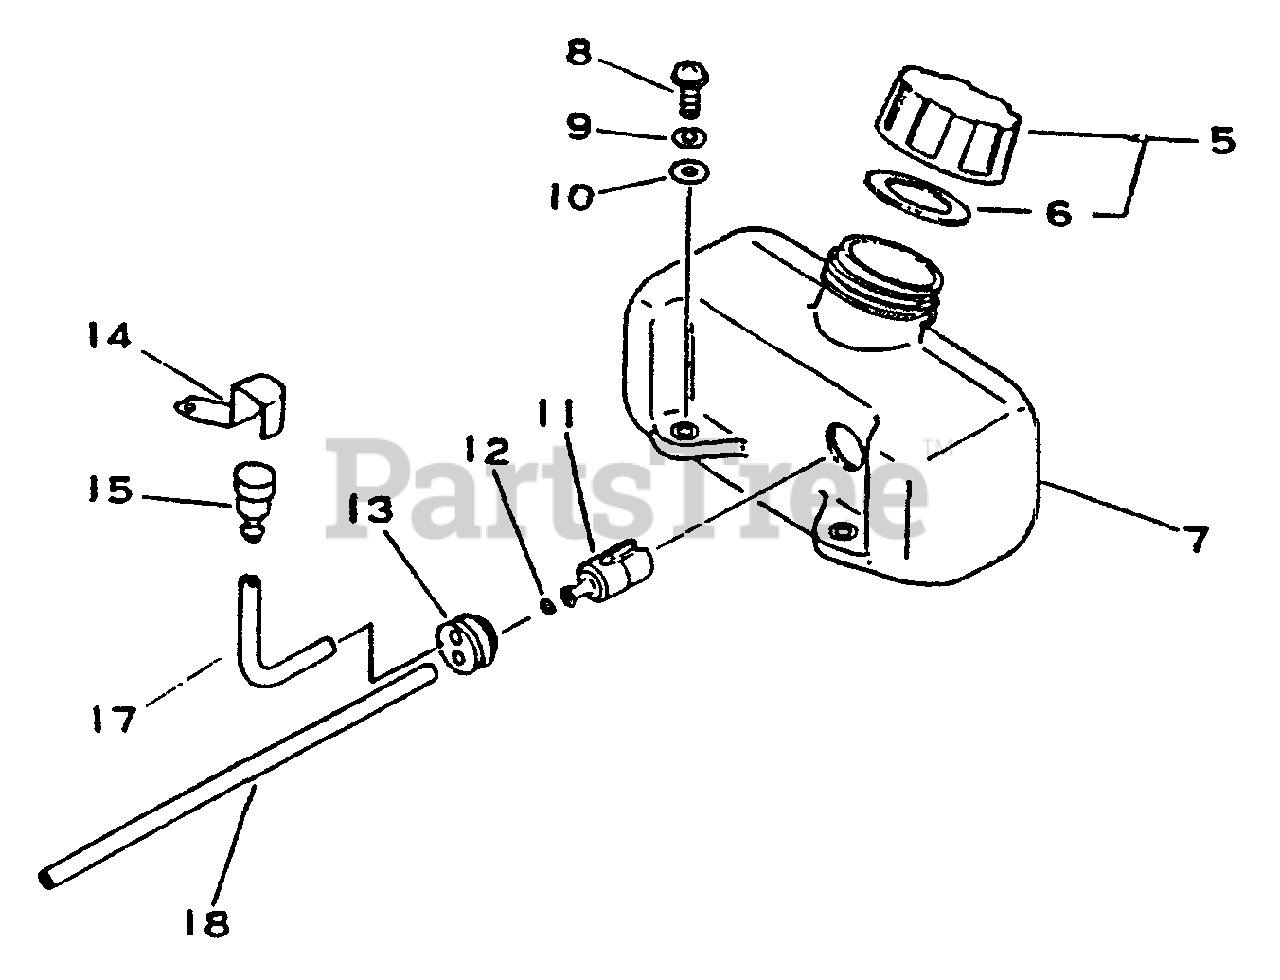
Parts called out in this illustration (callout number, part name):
5	CAP ASSY
6	GASKET, FUEL CAP
7	TANK, FUEL
8	SCREW 5×16
9	WASHER, SPRING 5
10	WASHER 5.5×12×0.8
11	FILTER, FUEL
12	CLIP 6 MM
13	GROMMET, FUEL
15	VENT ASSY
17	PIPE, FUEL RETURN 3×6×70
18	PIPE, FUEL 3x-5x-180
